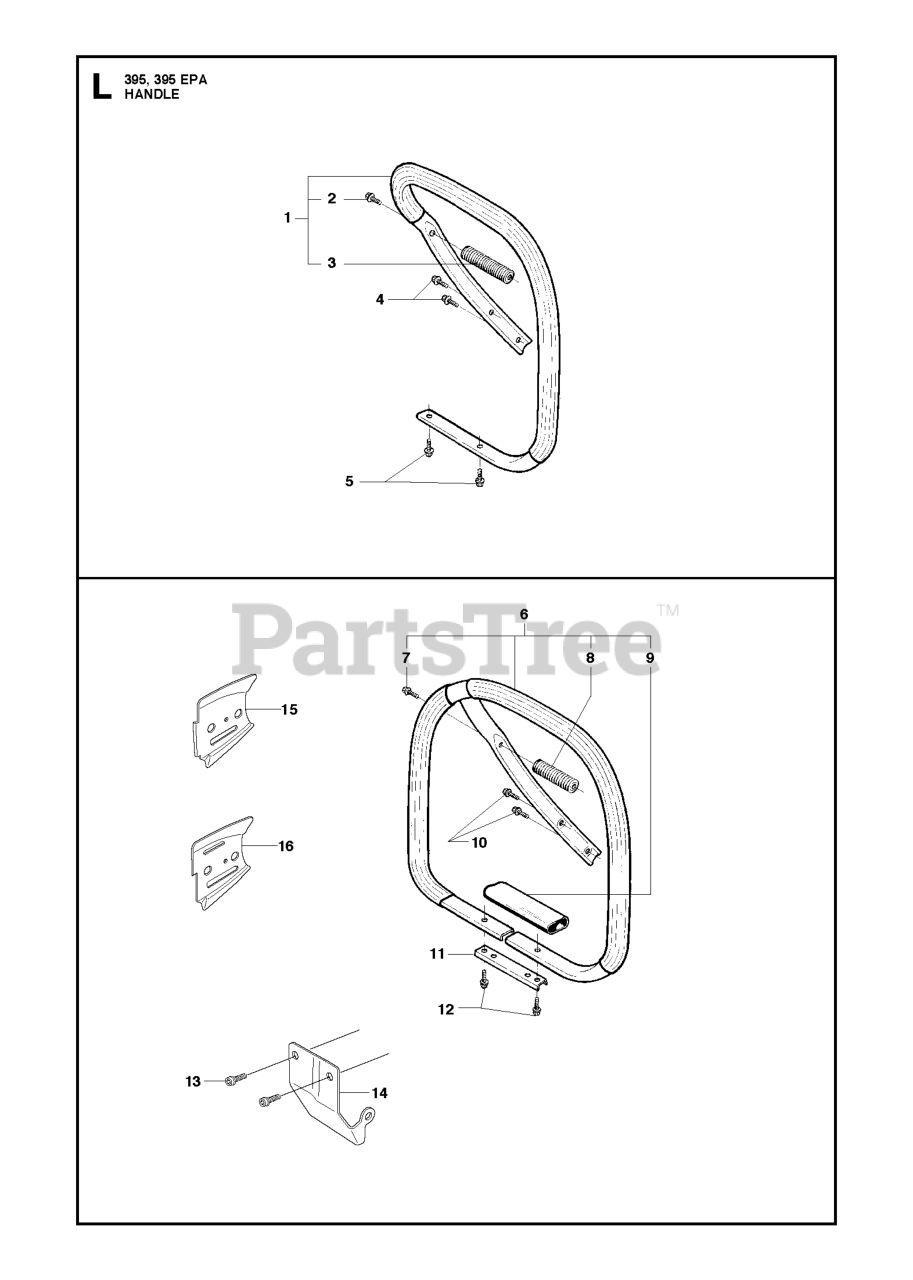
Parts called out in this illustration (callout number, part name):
1	FRONT HANDLE
6	FRONT HANDLE/WRAP
6	WRAP HANDLE, HEATED 395
13	SCREW
14	PROTECTIVE PLATE
15	GUIDE PLATE
16	GUIDE PLATE
